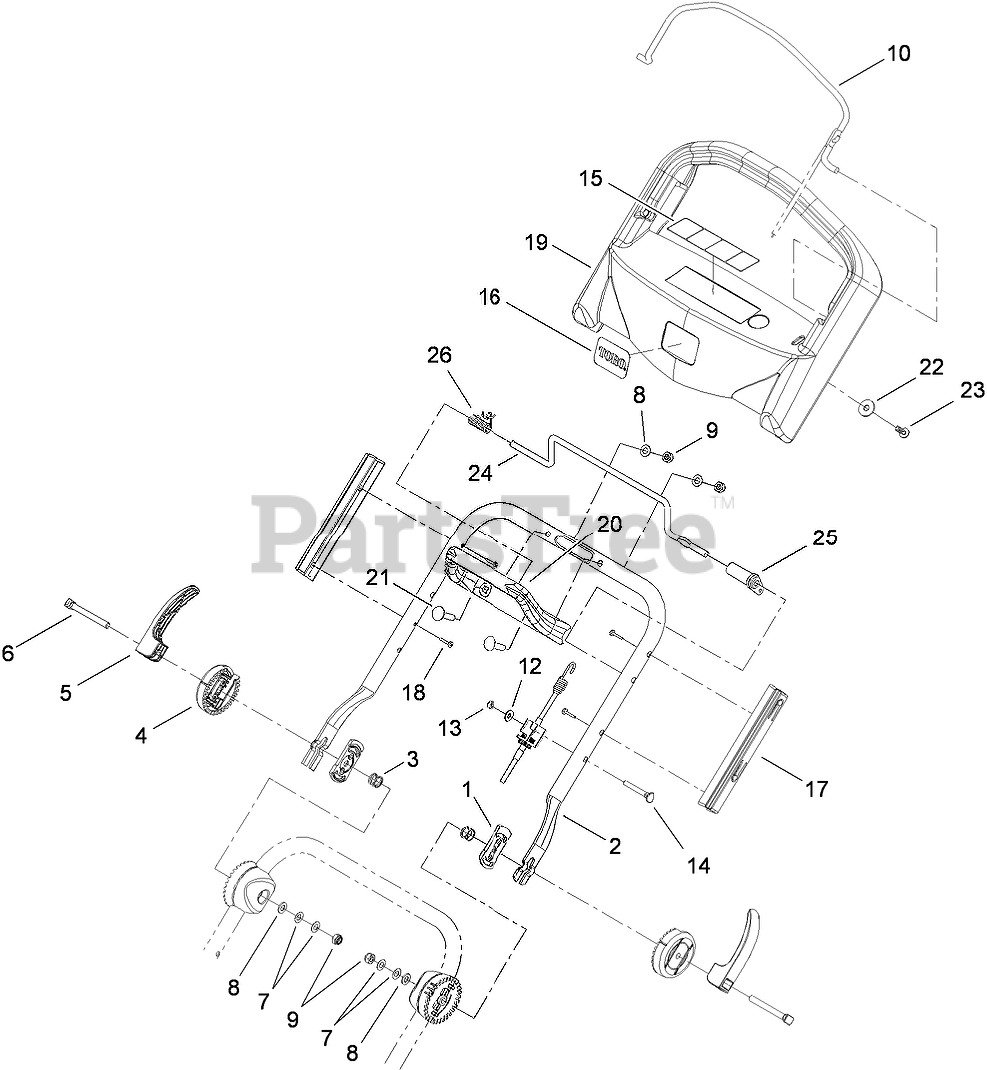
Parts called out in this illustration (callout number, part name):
1	PLATE-ADJUST, HANDLE
2	HANDLE-UPPER
3	SPRING-ADJUST, HANDLE
4	MOUNT-HANDLE, UPPER
5	LEVER-LOCKING, HANDLE
6	BOLT-T HEAD, UPPER
7	WASHER-SPRING
8	WASHER-PLAIN
9	NUT-HEX
10	BAIL-BRAKE
12	WASHER-FLAT
13	NUT-HEX
14	BOLT-CARRIAGE
17	GUIDE-HANDLE, CONTROL
18	SCREW-PPH
19	HANDLE-CONTROL
20	HANDLE-ASSIST, TRACTION
21	BOLT-RH
22	WASHER-PLAIN
23	SCREW-ROUND HEAD, POZIDRIVE
24	BAR-CONTROL, TRACTION
25	LEVER-TRACTION
26	Spring-Torsion
